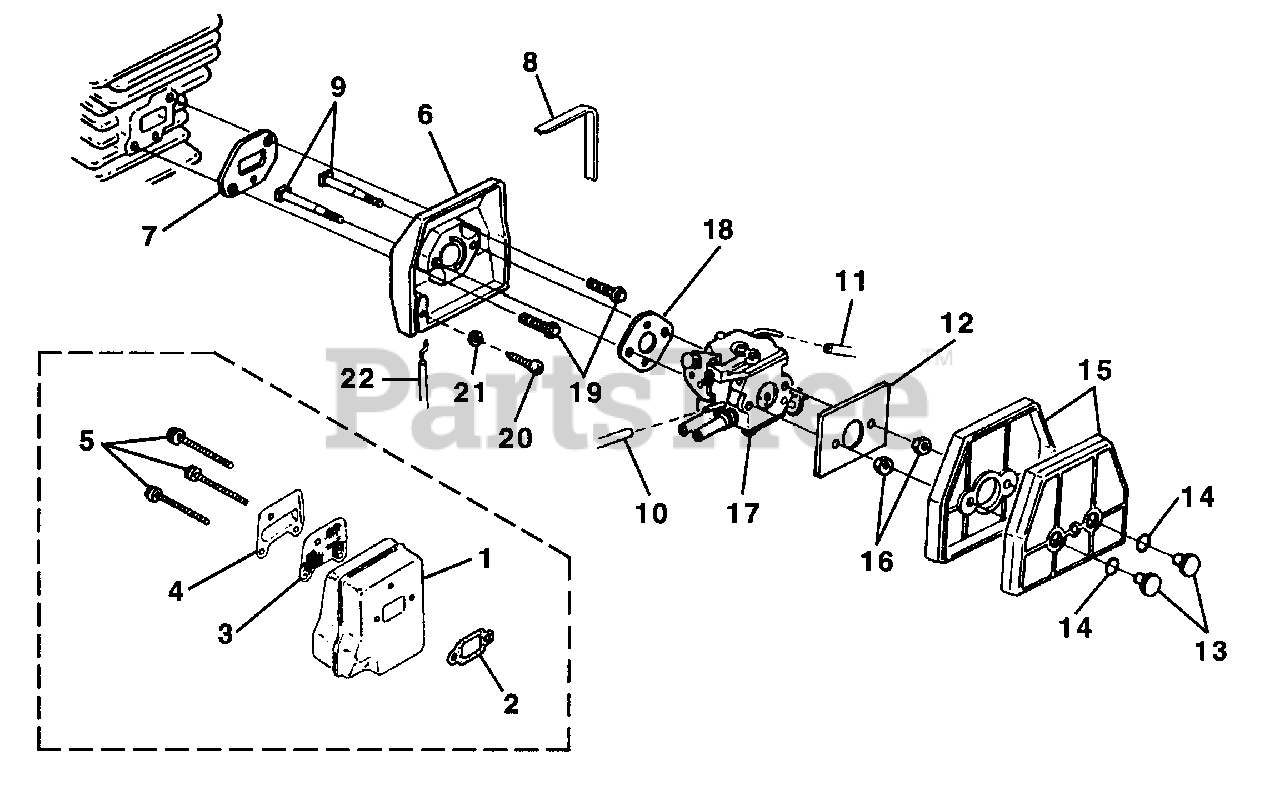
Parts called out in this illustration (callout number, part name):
1	MUFFLER-Complete
2	GASKET-Muffler
3	SCREEN-Spark Arrestor
4	COVER-Exhaust
5	SCREW-Sems (10-24 x 2 1/4)
6	SPACER-Carburetor
7	GASKET-Carburetor Spacer
8	FOAM-Adhesive
9	SCREW-Carburetor Retainer
10	TUBING-Rubber (4 3/4")
11	TUBING-Rubber (9")
12	RETAINER PLATE
13	RETAINER NUT-Filter
14	"O" RING
15	AIR FILTER
16	NUT-Hex (8-32)
17	CARBURETOR
18	GASKET-Carburetor
19	SCREW-Mach. Hex Hd. (8-32 x 7/8")
20	SCREW-Thread Form. (6-19 x 1/2")
21	WASHER-Flat (#6)
22	CABLE-Throttle
